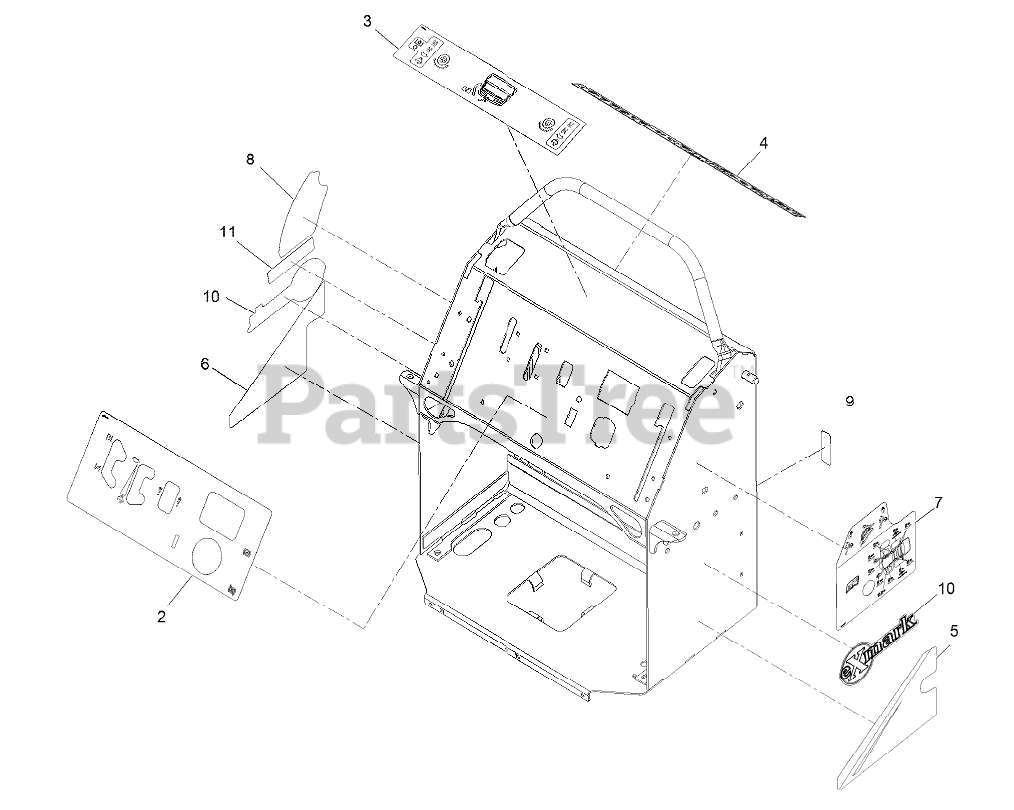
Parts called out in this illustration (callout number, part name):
2	DECAL-CONTROL PANEL EFI
3	DECAL-MOTION CONTROL
4	DECAL-WARNING
5	DECAL-LH PANEL
6	DECAL-RH PANEL
7	DECAL-SERVICE AID
8	DECAL-HEIGHT OF CUT
9	DECAL-FUSE
10	DECAL-EXMARK LOGO
11	DECAL-ARRESTER, SPARK
